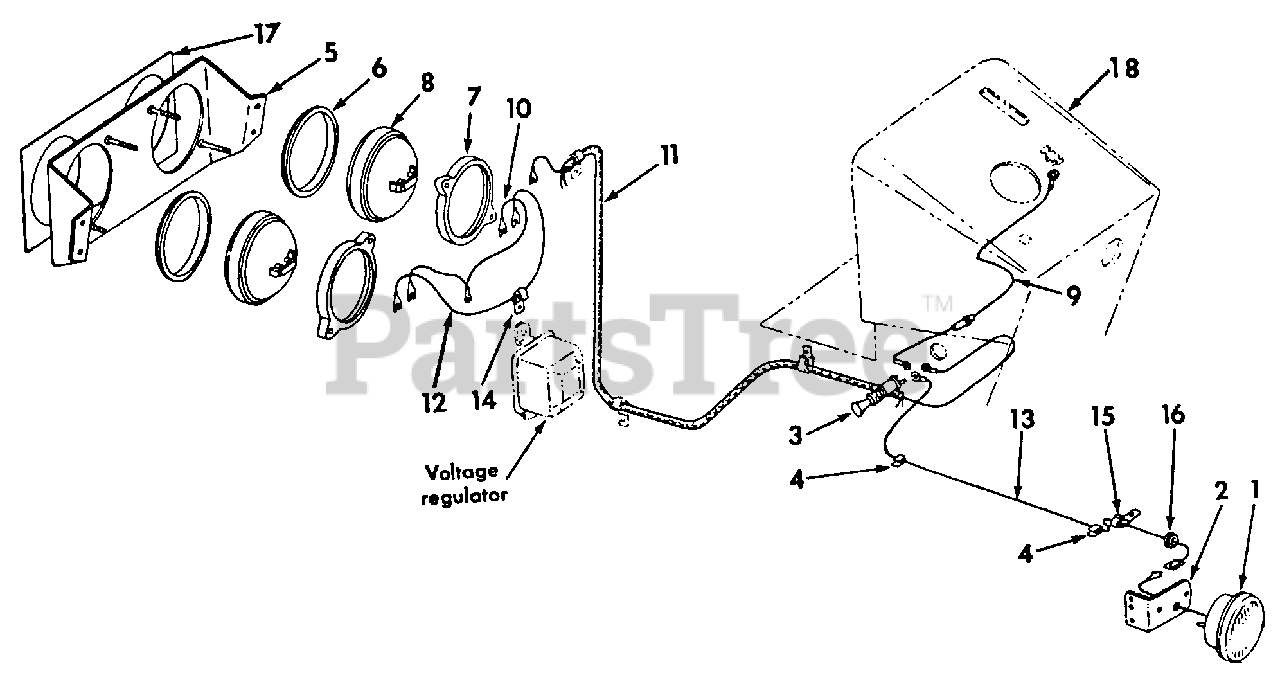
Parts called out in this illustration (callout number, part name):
1	Taillight Assy
2	Bracket, Taillight Mounting
3	Switch Assy, Lighting
4	Clip, Taillight Cable
5	Panel Assy, Headlight Mounting
6	Ring, Headlight Retaining
7	Ring, Headlight Clamp
8	Unit Assy, Sealed Beam Headlight
9	Cable Assy, Lighting Switch to Charge Indicator
10	Cable Assy, Headlight to Ground
11	Harness Assy, Cable
12	Cable Assy, RH Headlight to LH Headlight
13	Cable Assy, Lighting Switch to Taillight
14	Clip, Headlight Cable
15	Clip, Lighting Switch to Taillight Cable
16	Grommet, Taillight Cable
17	Product Graphic, Headlight Panel Indicator
18	Pedestal Assy
